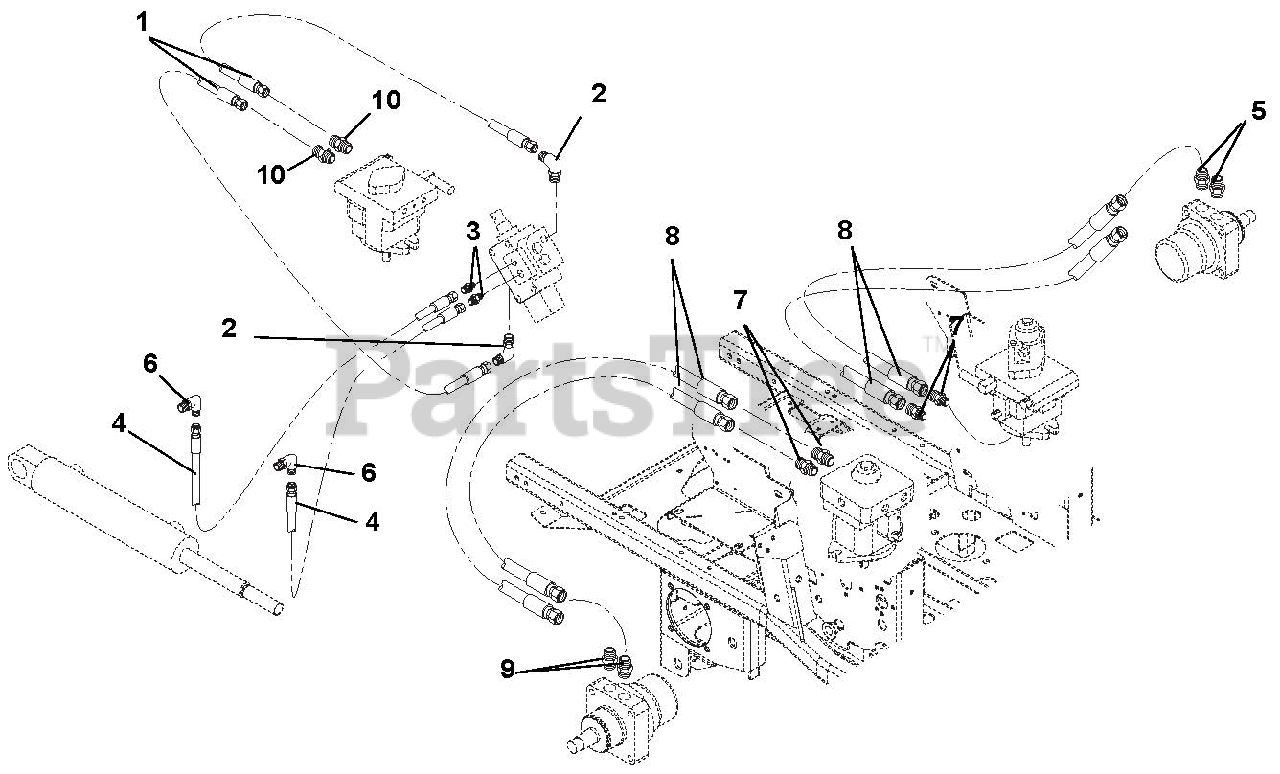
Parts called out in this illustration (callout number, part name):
1	Hose, Hydraulic
2	Hydraulic, Fitting Elbow
3	Adapter, 4 – 6F5OLO
4	Hose, Hydraulic
5	Fitting, Hydraulic Straight, 8 – 10 F5OLO – S
6	Fitting, Hydraulic, 4 C5OLO
7	Adapter, Face Seal 8 x 8 .50 O-Ring
8	Hose, Hydraulic .50
9	Adapter, Hydraulic Steel, M10 O – M8F
10	Fitting, Hydraulic, 4 F5OLO
